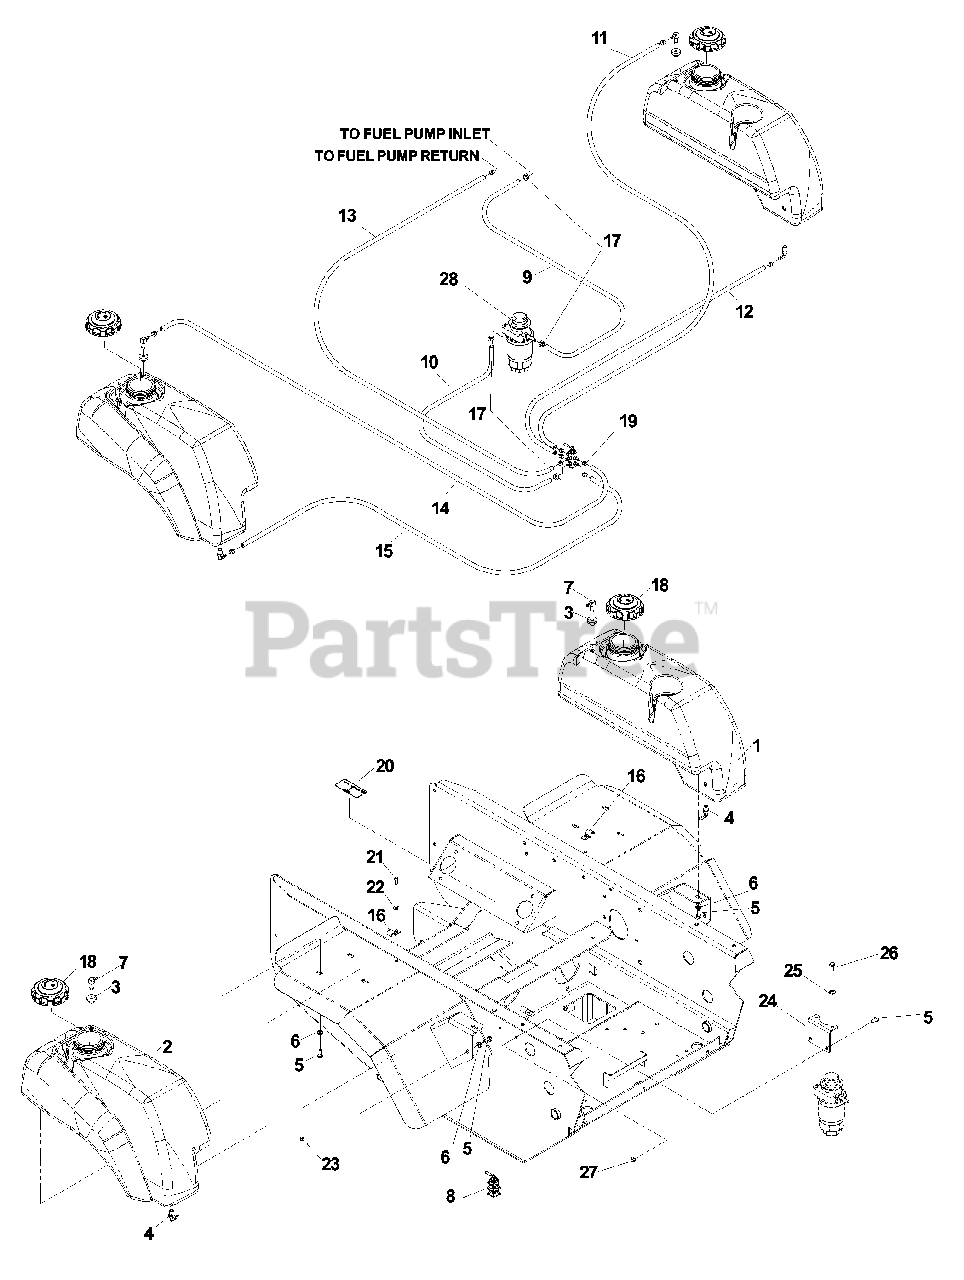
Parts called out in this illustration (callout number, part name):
1	Fuel tank, left
2	Fuel tank, right
3	Grommet, rubber
4	Hose barb, 90°
5	Bolt, 5/16-18 x 3/4
6	Washer, 5/16, sealing
8	Valve, fuel
9	Fuel line (38")
10	Fuel line (35")
11	Fuel line (79")
12	Fuel line (57")
13	Fuel line (54")
14	Fuel line (34")
15	Fuel line (13")
18	Cap, diesel fuel
19	Hose clamp
20	Decal, fuel valve
21	Bolt, 1/4-20 x 3/4
22	Washer, 1/4
23	Nut, 1/4-20, nyloc
24	Mounting bracket
25	Lockwasher, 5/16
26	Bolt, M8-1.25 x 20
27	Nut, 5/16-18, nyloc
28	Fuel filter/pump assembly
